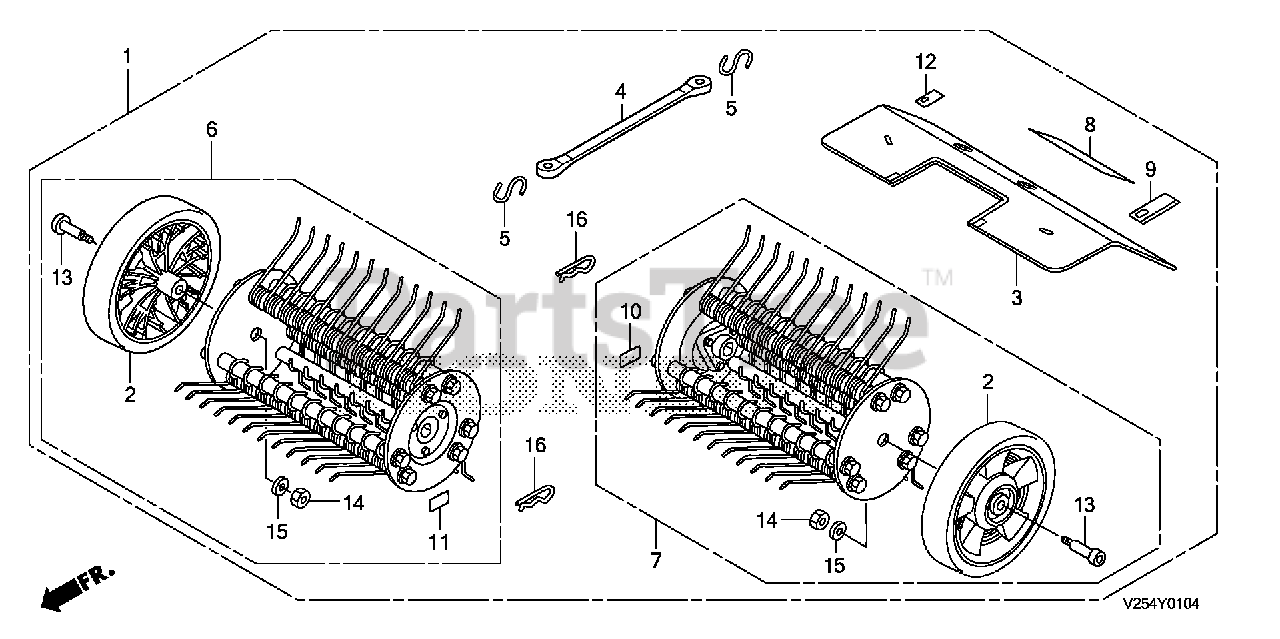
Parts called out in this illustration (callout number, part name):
1	DE-THATCHER KIT (USA)
2	WHEEL, RR. (NOT AVAILABLE)
3	FENDER, DE-THATCHER
4	STRAP, FENDER (NOT AVAILABLE)
5	HOOK, S (NOT AVAILABLE)
6	DE-THATCHER, R. (NOT AVAILABLE)
7	DE-THATCHER, L. (NOT AVAILABLE)
8	LABEL, TINE DANGER (ENGLISH)
9	MARK, OIL LEVEL CHECK (ENGLISH)
10	DECAL, L. (NOT AVAILABLE)
11	DECAL, R. (NOT AVAILABLE)
12	MARK, DE-THATCHER NOTICE (ENGLISH)
13	BOLT, SHOULDER (3/8-16X1-1/2IN) (NOT AVAILABLE)
14	NUT, CENTERLOCK (3/8-16)
15	WASHER, LOCK (3/8IN) (NOT AVAILABLE)
16	PIN, LOCK (17MM)
